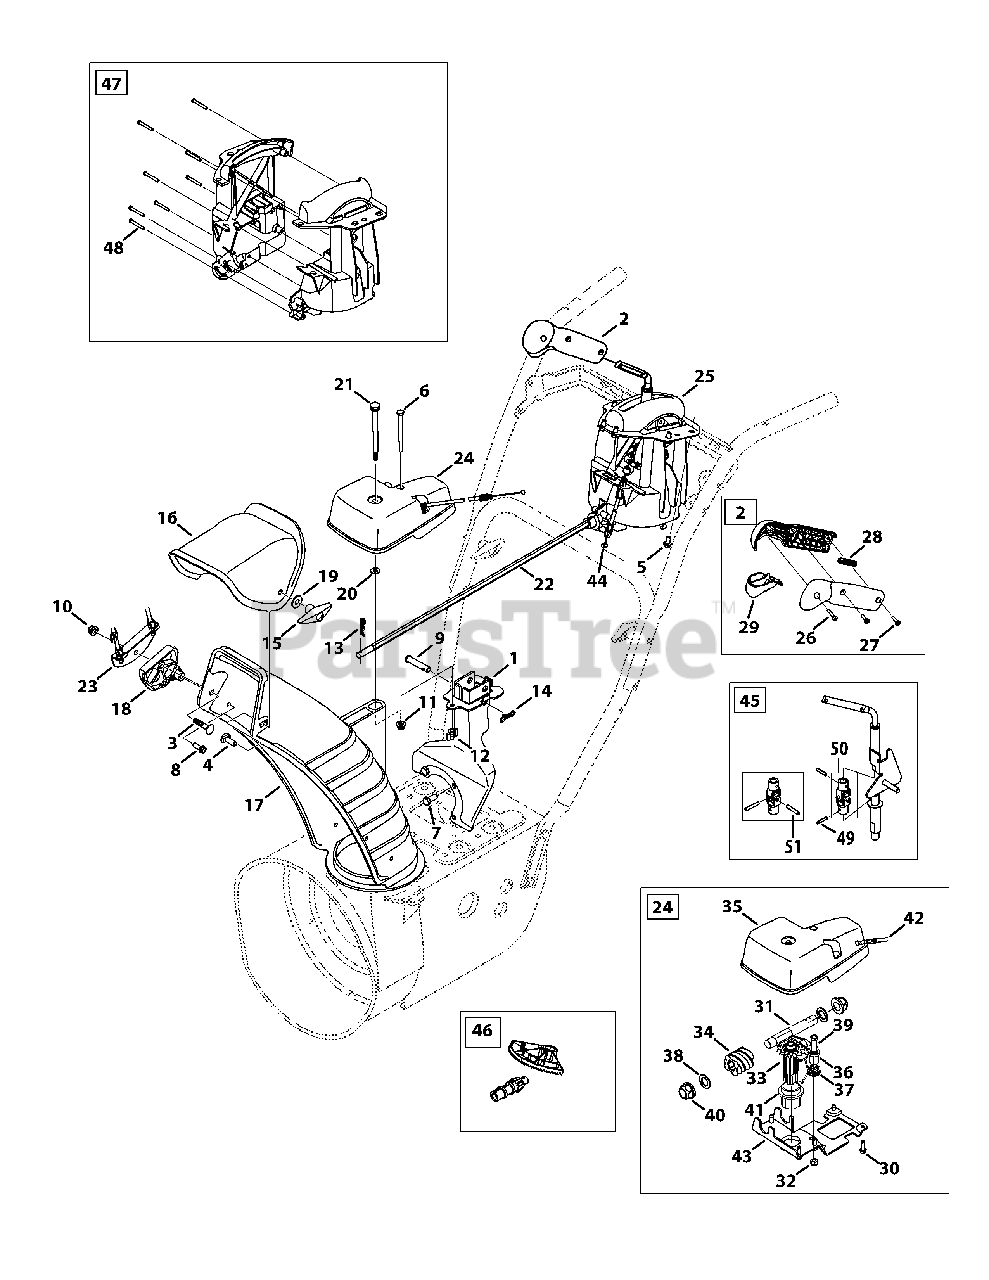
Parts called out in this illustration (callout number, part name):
1	Chute Support Bracket
2	Handle Assembly
3	Bolt, Carriage, 5/16-18 x 1.50
4	Bolt, Carrier, 5/16-18 x 1.00
5	Screw, HL, 1/4-15 x 0.50
6	Hex Head Screw, 1/4-20 x 3.00
7	Hex Head Screw, 5/16-24 x .750
8	Screw, HL, 1/4-15 x 0.750
9	Clevis Pin, 3/8 x 1.87
10	Nut, Flangelock, 5/16-18
11	Nut, Flangelock, 1/4-20
12	Wing Nut, 1/4-20
13	Internal Cotter Pin
14	Bow-Tie Cotter Pin
15	Wing Knob, 5/16-18
16	Chute, Upper
17	Chute, Lower
18	Cable Guide, Chute Tilt
19	Washer, Flat, .349 x .879
20	Washer, Flat, .25 x .630
21	Screw, Shoulder, .312 x 3.5 x 1/4-20
22	Chute Rod, 3/8 Hex
23	Cable Bracket
24	Gearbox Assembly, Chute Rotation
25	Chute Control, 4-Way
26	Screw, #8 x 1.00
27	Screw, 8-32 x .750
28	Joystick Plug
29	Joystick Trigger
30	Screw, 12-16 x .75
31	Hex Shaft
32	Hexlock Nut, 1/4-28
33	Gear, 14 T
34	Worm
35	Gear Cover
36	Pawl Lock
37	Torsion Spring, .721 ID x .474
38	Washer, Flat, .625 x 1.0 x .067
39	Screw, Shoulder, .340 x .950 x 1/4-28
40	Hex Bearing
41	Flange Bearing
42	Cable Lock
43	Gear Bracket
44	4-Way Cable
44	Cable Clip
45	Shift Assembly
46	Gear Set Assembly
47	Handle Housing Assembly
48	Screw, #8-18 x 1.250
49	Pin, Roll
50	Block, Asm Joint
51	Pin, Roll
